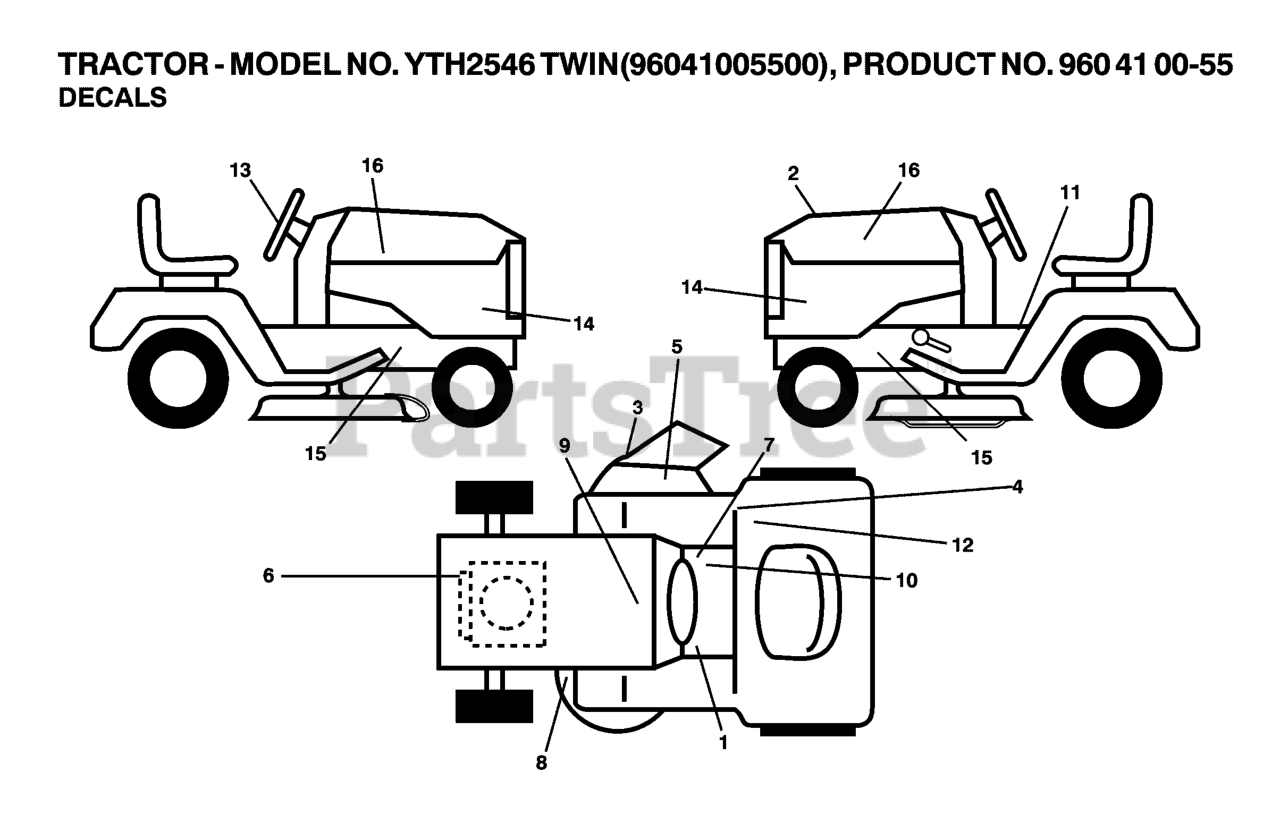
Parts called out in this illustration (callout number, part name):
1	DECAL
2	DECAL.HOOD.TOP.INSERT.
3	DECAL, DEFLECT WARNING
4	DECAL 80 DBA
5	DECAL.INTERNATIONL.CUTFINGER
6	DECAL
7	DECAL PARK BRAKE
8	DECAL V BELT SCHEMATIC
9	DECAL BTRY SYMBOLS
10	DECAL
11	LABEL
12	DECAL
13	DECAL.WHEEL.STRG.LGN.H
16	DECAL.HOOD.NAMELOGO.HUSQ
